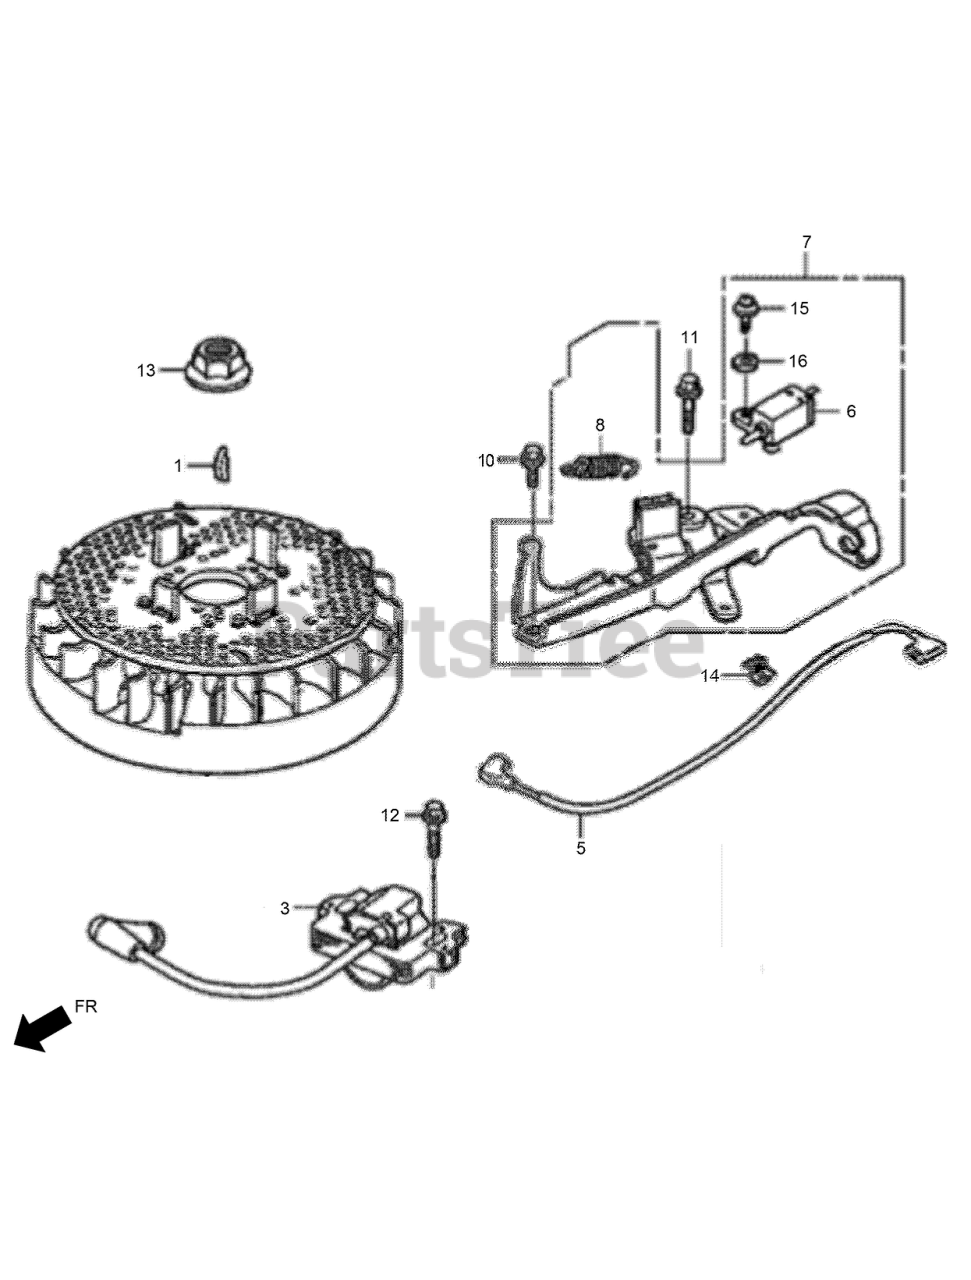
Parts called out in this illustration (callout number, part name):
1	KEY-SPECIAL WOODRUFF-25X18
3	COIL ASM-IGNITION
5	CORD-STOP SWITCH
6	SWITCH ASM-ENGINE STOP
7	BRAKE ASM (from S/N 3238210)
7	BRAKE ASM (to S/N 3238209)
8	SPRING-BRAKE LEVER
10	BOLT-FLANGE-6X14
11	BOLT-FLANGE-6X23
12	BOLT-FLANGE-6X20
13	NUT-SPECIAL-14MM
14	CLIP A-CABLE
15	SCREW-WASHER-4X12
16	WASHER-PLAIN-4MM
